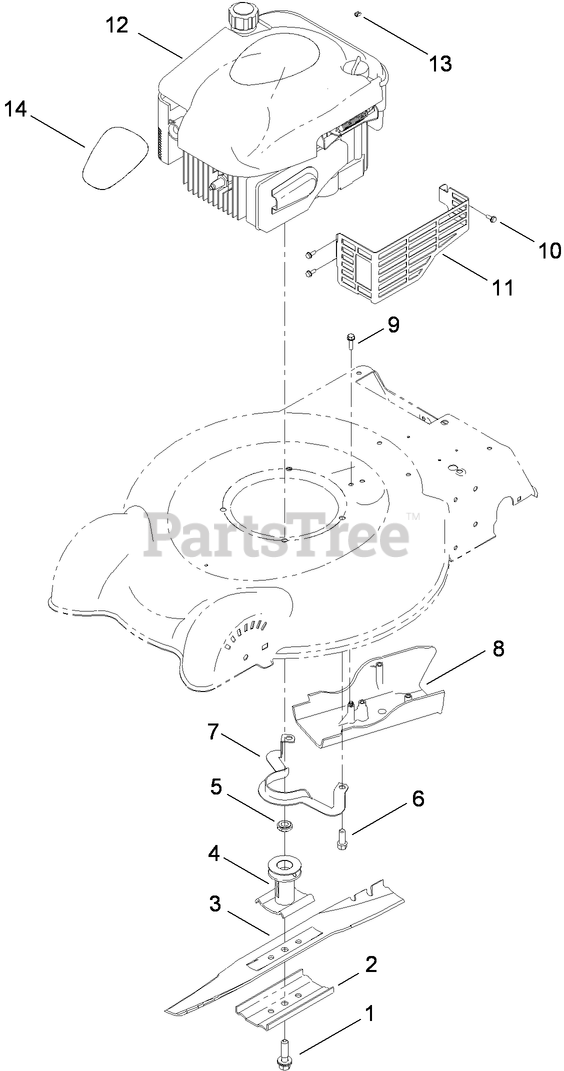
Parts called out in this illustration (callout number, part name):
2	SUPPORT-BLADE
4	DRIVER-BLADE
5	SPACER-DRIVER
6	SCREW-TAPTITE
7	GUIDE-BELT
8	COVER-BELT
9	SCREW-HWH
10	SCREW-TAPTITE
11	SHIELD-MUFFLER
13	STOP-ROPE
14	DECAL-ENGINE
